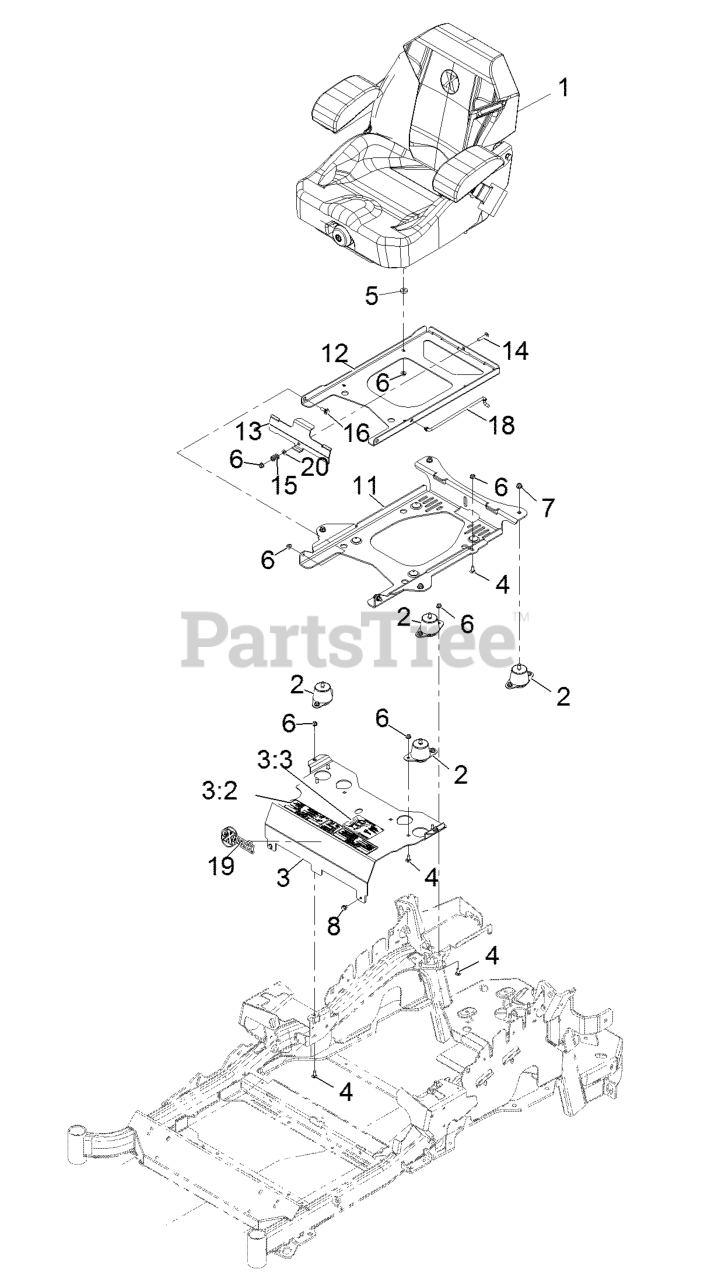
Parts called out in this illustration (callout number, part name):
1	KIT-SUSPENSION SEAT
2	ISOLATOR-SEAT
3	MOUNT-SEAT
3:2	DECAL-CONSOLE
3:3	DECAL-SERVICE AID
4	SCREW-CARR
6	NUT-HF, NI
7	NUT-HF, NI
11	PLATE-TILT, SEAT SUPPORT
12	PLATE-FRAME, SEAT
13	PLATE-LATCH, SEAT
14	BOLT-CARR
15	SPRING-COMPRESSION
16	SCREW-SHOULDER
18	ROD-PROP
20	WASHER-PLAIN
